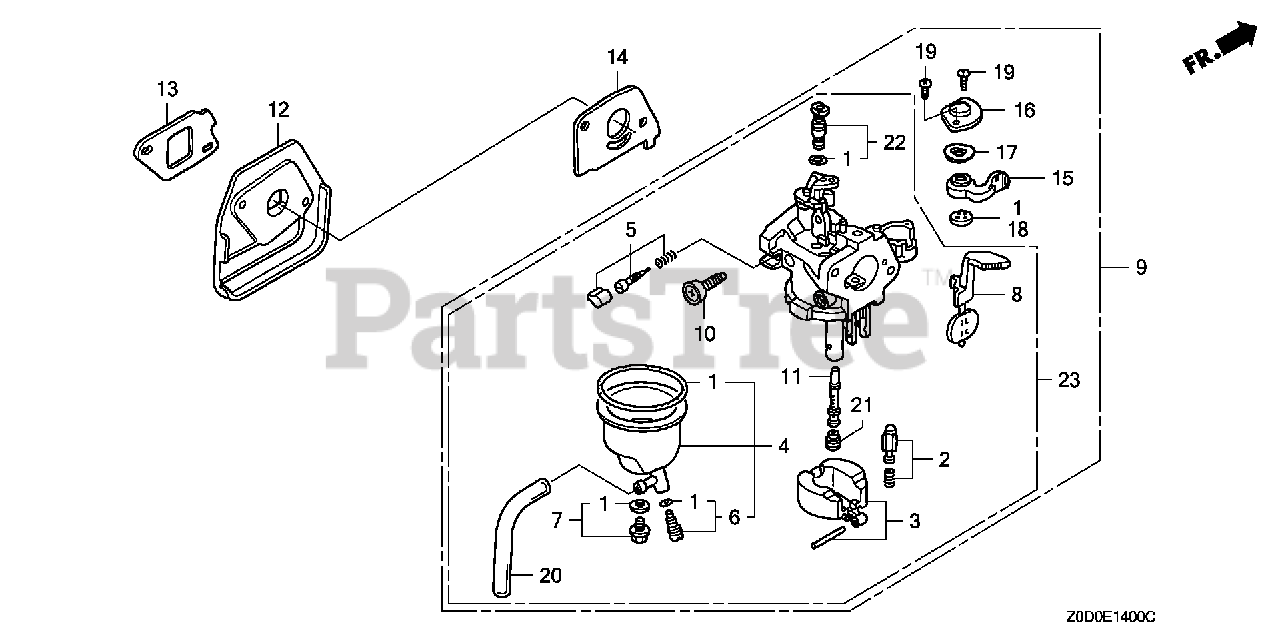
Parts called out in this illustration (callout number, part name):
1	GASKET SET
2	VALVE SET, FLOAT (SEAT NOT INCLUDED)
4	CHAMBER SET, FLOAT
5	SCREW SET, PILOT
6	SCREW SET, DRAIN
7	SCREW SET
9	CARBURETOR ASSY. (BF32F B)
9	CARBURETOR ASSY. (BF32F C)
10	SCREW, THROTTLE STOP
11	NOZZLE, MAIN
12	INSULATOR, CARBURETOR
13	GASKET, INSULATOR
14	GASKET, CARBURETOR
15	LEVER, PETCOCK
16	PLATE, LEVER SETTING
17	SPRING, PETCOCK LEVER
18	GASKET, PETCOCK
19	SCREW, PAN (3X6)
20	BULK HOSE, VINYL (3.5X6.5X8000) (3.5X6.5X100)
21	JET, MAIN (#55)
21	JET, MAIN (#58)
21	JET, MAIN (#60)
22	JET SET, PILOT (#35)
